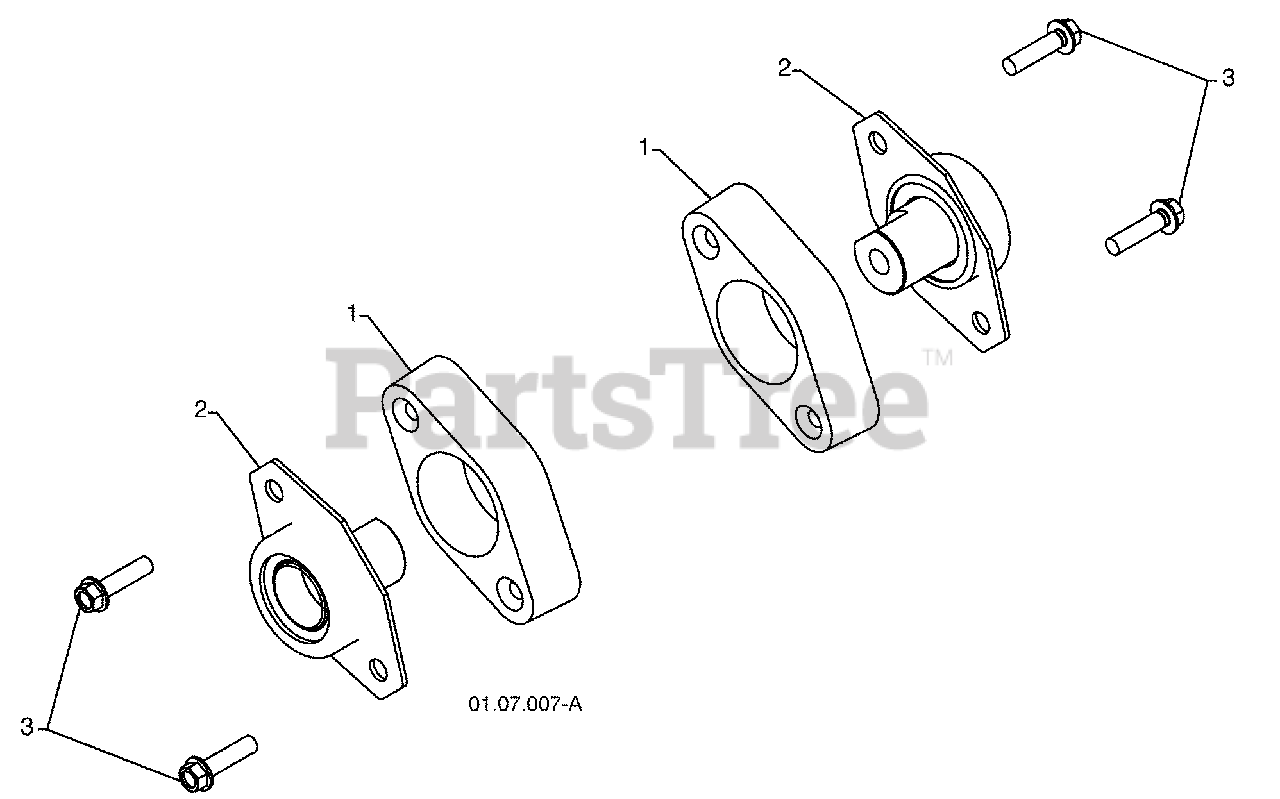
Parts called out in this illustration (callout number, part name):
1	PLASTIC RETAINER
2	AUGER BALL BEARING
3	SCREW 5/16-18 X 1.00
